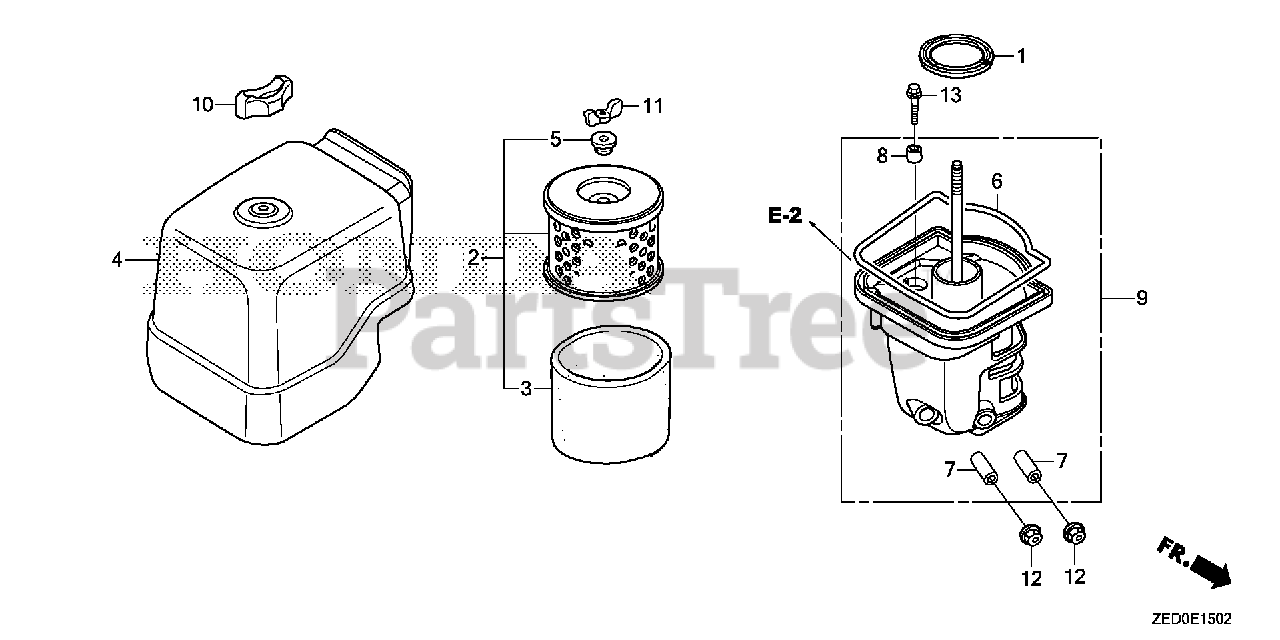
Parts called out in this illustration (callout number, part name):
1	GASKET, ELBOW
2	ELEMENT, AIR CLEANER
3	FILTER (OUTER)
4	COVER ASSY., AIR CLEANER
5	GROMMET, AIR CLEANER
6	SEAL, AIR CLEANER COVER
7	COLLAR, AIR CLEANER Use from Engine SN 1786085.
8	COLLAR B, AIR CLEANER
9	ELBOW, AIR CLEANER
10	NUT, AIR CLEANER
11	WINGNUT, TOOL BOX SETTING
12	NUT, FLANGE (6MM)
13	BOLT, FLANGE (6X20)
